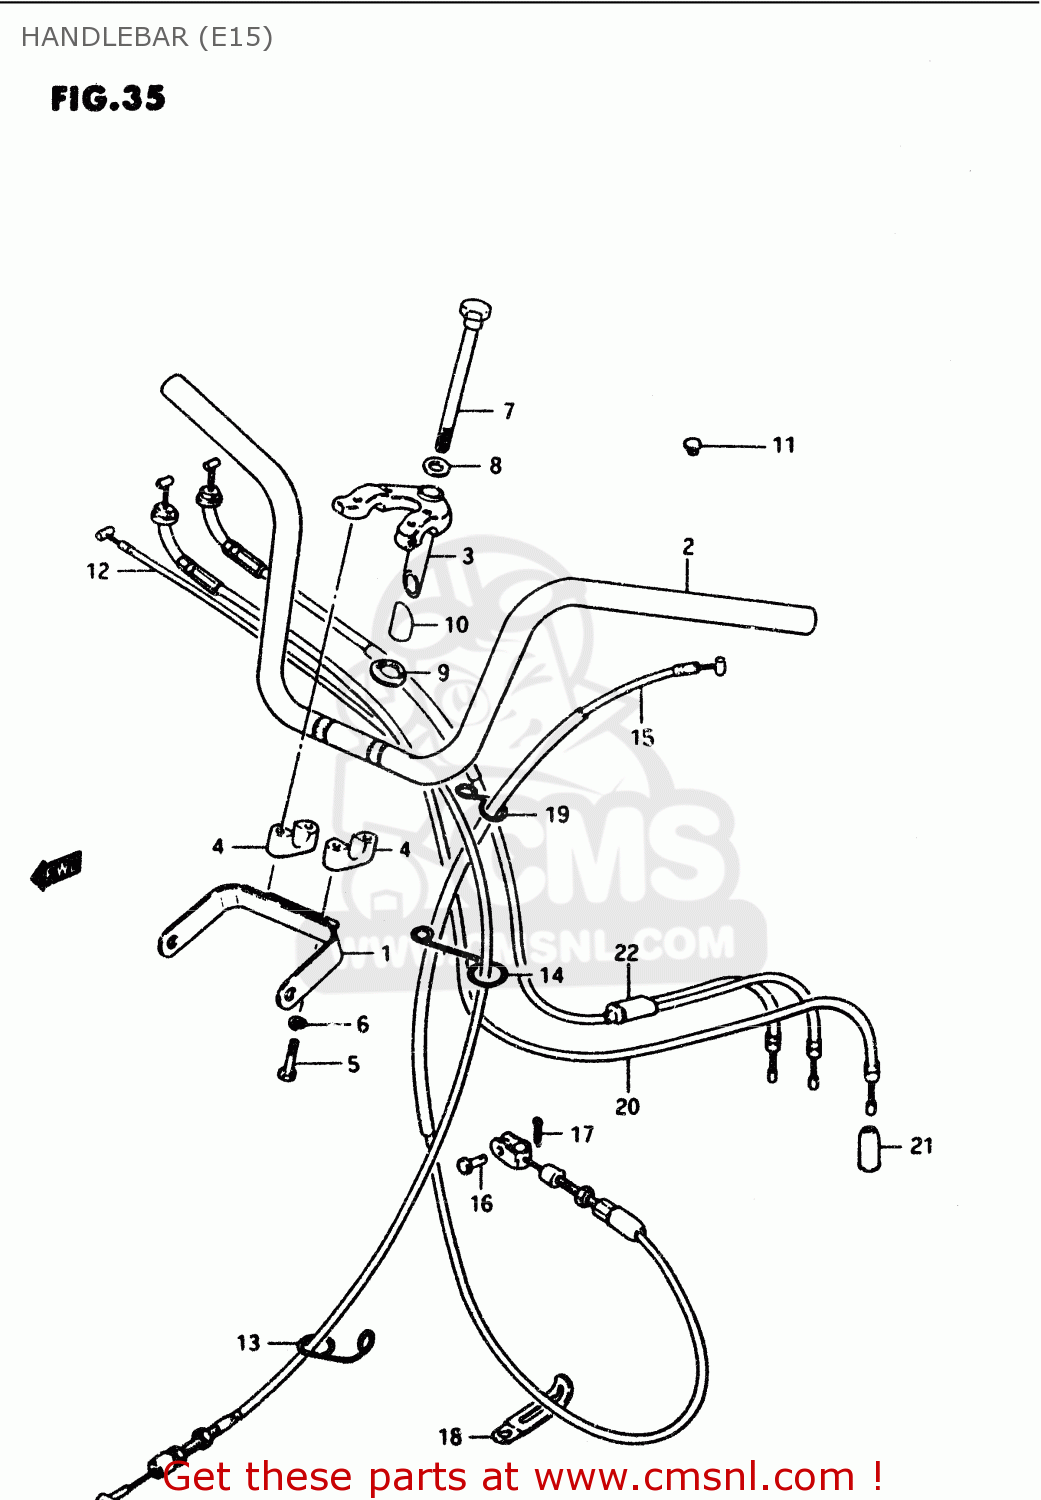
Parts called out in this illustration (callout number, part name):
1	BRACKET,HEAD LAMP HOUSING
2	HANDLEBAR
3	BRACKET,HANDLEBAR
4	HOLDER,HANDLE UPR
5	BOLT
6	WASHER,LOCK,8.
7	BOLT(12X114)
8	WASHER
9	STOPPER
10	STOP,HANDLE EXPANDER
11	CAP
12	CABLE,FR BRAKE
13	GUIDE
14	GUIDE,FR BRAKE CABLE UPR
15	CABLE ASSY,CLUTCH
16	PIN(L:13)
17	PIN
18	CLAMP
19	GUIDE,CABLE
20	CABLE ASSY, THROTTLE
21	SEAL,DUST(7X18X30)
22	CABLE ASSY,THROTTLE
